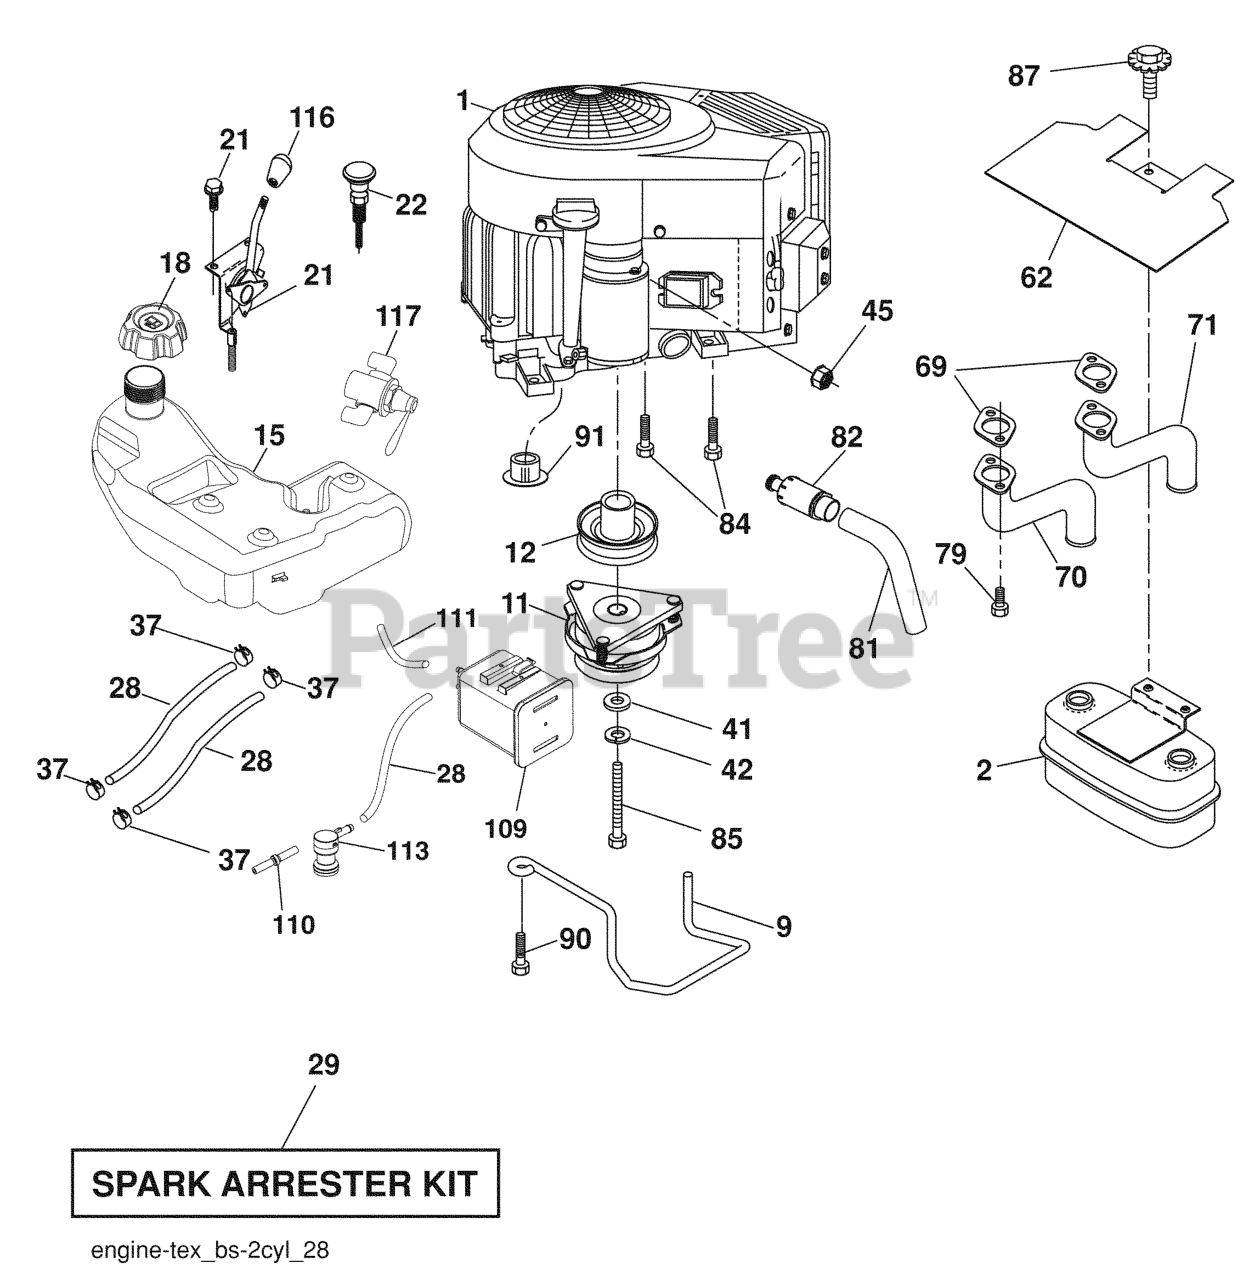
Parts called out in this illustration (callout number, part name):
2	MUFFLER.TWIN.CYL.LOW.TONE
9	KEEPER.BELT.ENGINE.4.2
11	CLUTCH.ELECTRIC.LT.48"*
12	PULLEY.ENGINE.TUFFTORQ
15	RP_TANK.ASM.4.GAL.CARB.2.PORT
18	CAP ASM
20	CONTROL.THROTTLE.PRO.
21	SCREW.#10 X 0.750.BOS
22	CONTROL.CHOKE.ERGO.PUSH-IN.BLA
28	LINE.FUEL.64"REAR.EMIS
29	KIT.SPARK ARRESTOR 794945 B&S
37	HOSE CLAMP
42	LOCKWASHER
45	NUT
62	RP SHIELD HEAT MUFFLER
69	GASKET.MUFF 806237 NOW 806425
70	EXHAUST.TUBE.MUFFLR.LH.VANG
71	EXHAUST.TUBE.MUFFLR.RH.VANG
79	SCREW.TUBE.MUFFLER.VANGUARD
81	TUBE, DRAIN OIL ASM.
82	PLUG DRAIN OIL EASY
84	SCREW.3/8-16
85	BOLT HEX 7/16-20X4-1/4"
87	BOLT 5/1618UNC X 3/4 W/ SEMS
90	SCREW 3/8-16X1
91	BUSHING.1.375OD
109	CANNISTER, CARBON
110	VALVE.ASM.ANTI-SLOSH
111	RP PURGE LINE
113	VALVE.SLANT.CARTRDG.90 DEG.TEX
116	RP KNOB SOFT TOUCH
117	VALVE FUEL RESERVE
